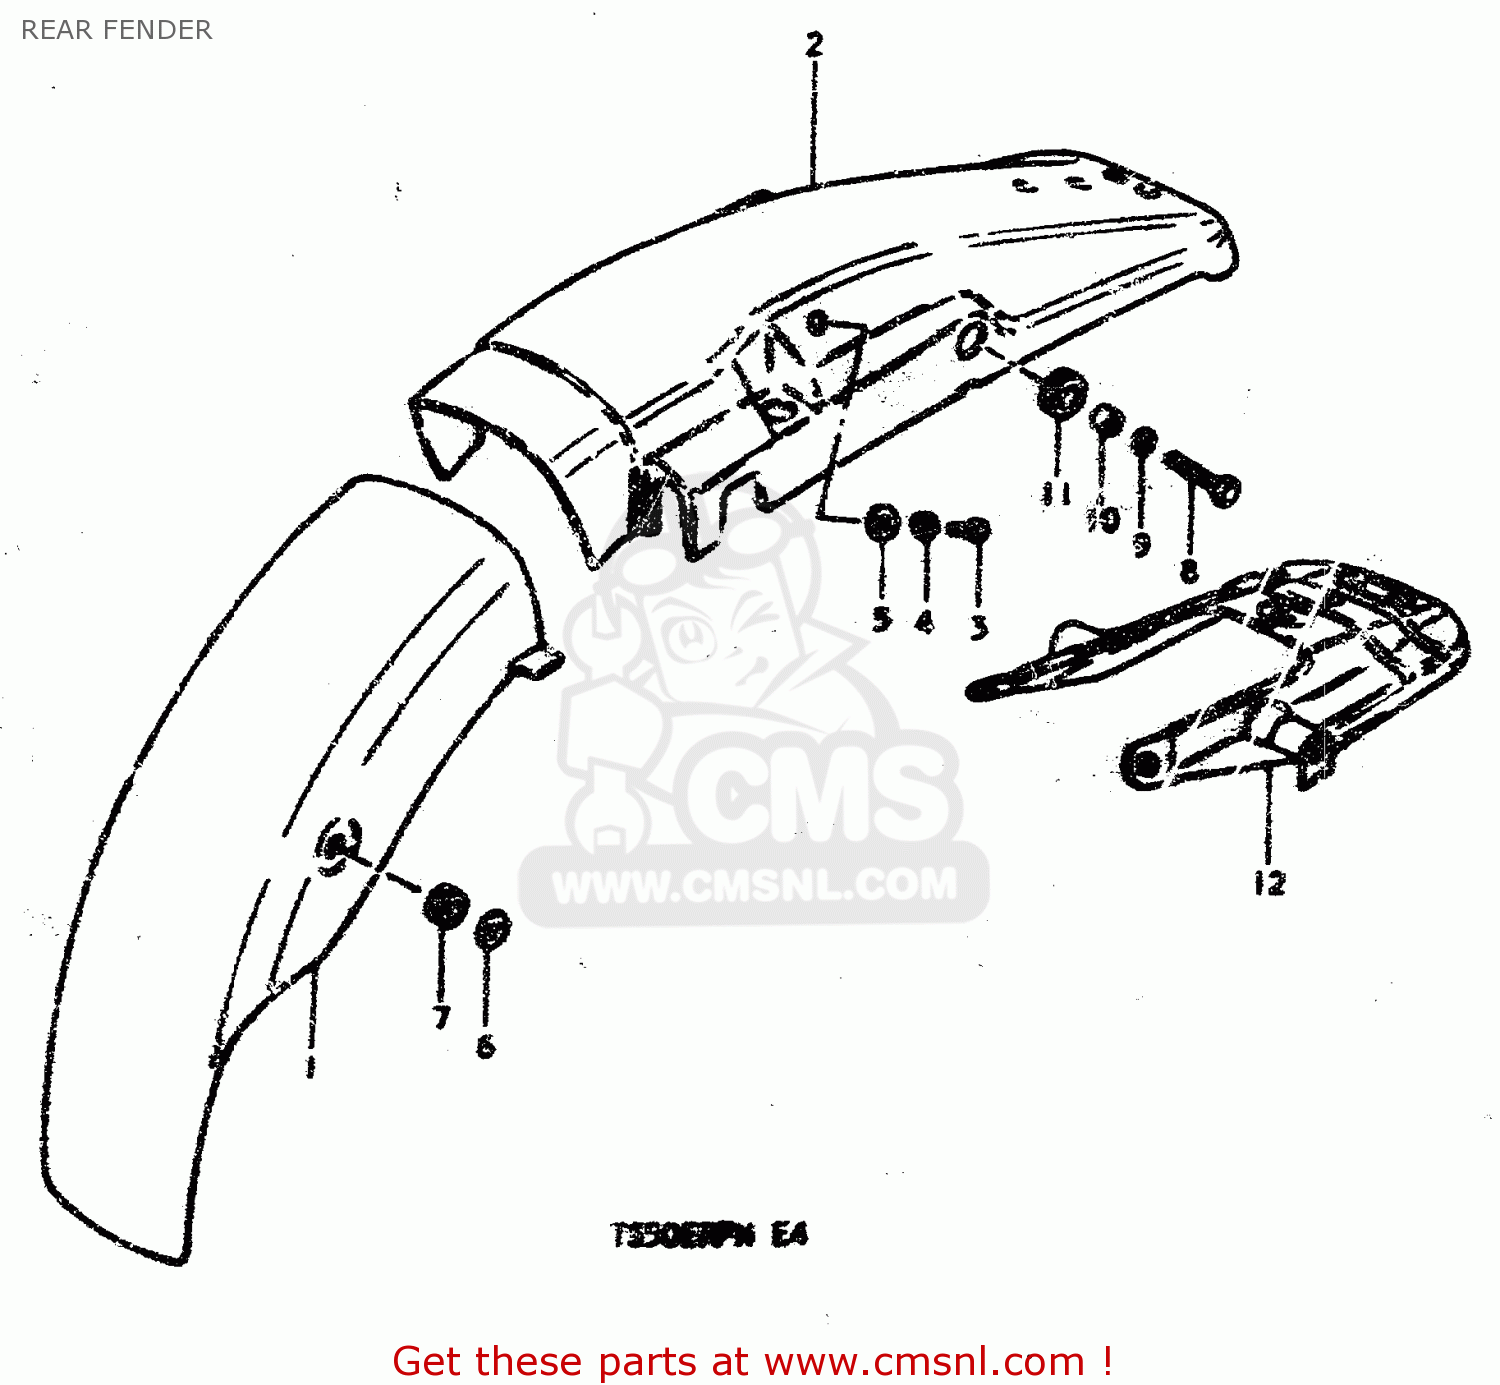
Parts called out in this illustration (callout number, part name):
1	BODY, REAR FENDER FRONT
2	BODY, REAR FENDER REAR
3	BOLT, UPPER
4	LOCK WASHER
5	WASHER
6	WASHER
7	CUSHION
8	BOLT 8X55
9	LOCK WASHER
10	SPACER (8.2X12X7.5)
11	CUSHION
12	REINFORCEMENT
